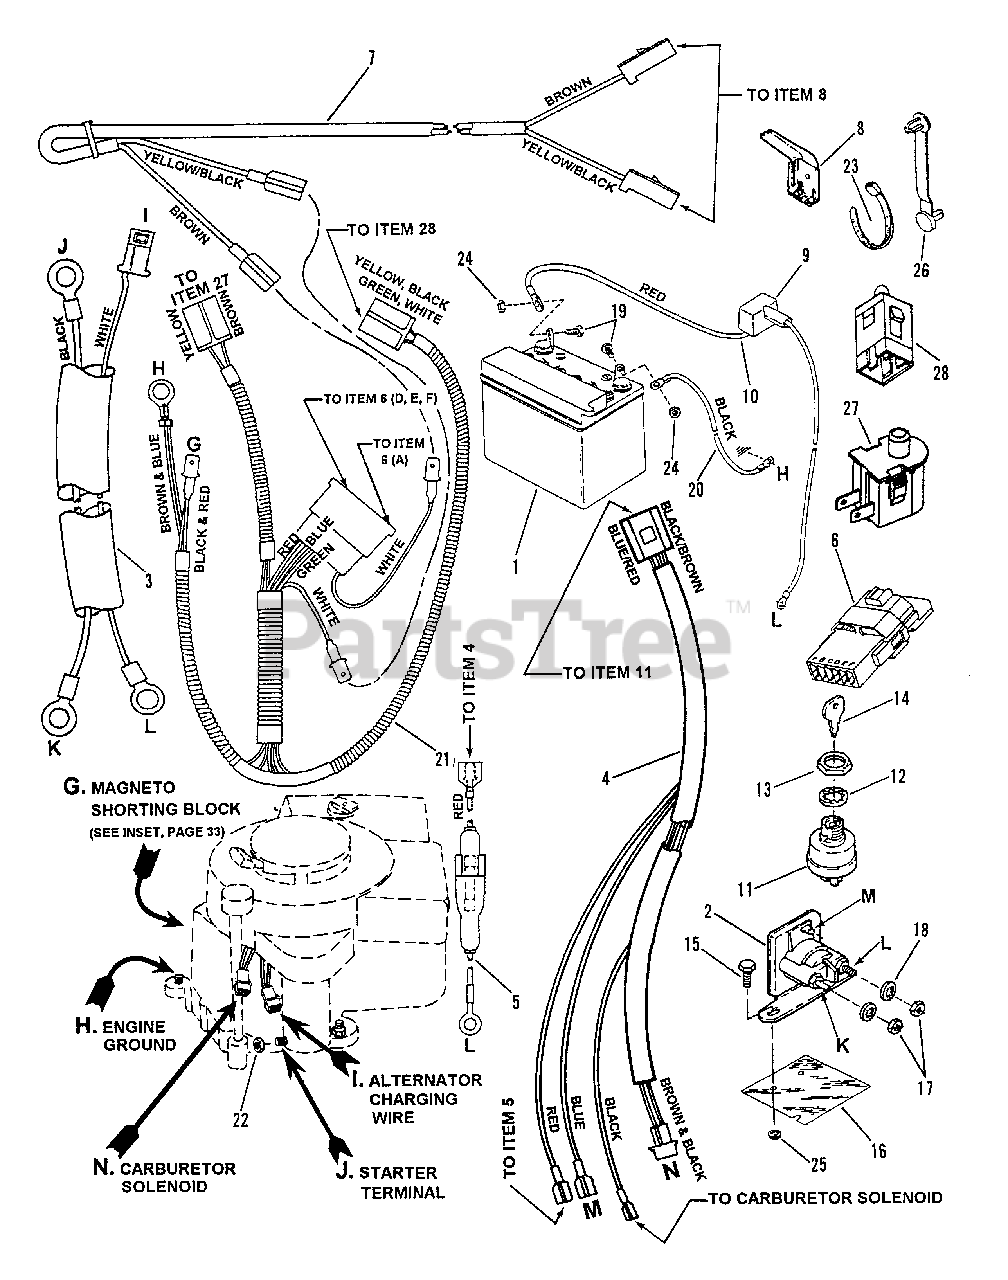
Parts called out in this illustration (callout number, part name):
1	KIT, 12V Dry Charge Battery
2	SOLENOID
3	HARNESS, Starter Wiring
4	HARNESS, Ignition Wiring
5	HOLDER, Fuse
6	INTERLOCK Module
7	HARNESS, (Deck Interlock Wiring)
8	SWITCH, Deck Interlock
9	COVER, Battery Cable
10	CABLE, Positive (Red)
11	SWITCH, Ignition
12	WASHER, 5/8 Internal Tooth Lock
13	NUT, 5/8-32 Hex
14	KEY, Switch
15	SCREW, 1/4-20 x 1/2" Self-Tapping
16	PROTECTOR, Solenoid
17	NUT, 1/4-20 Hex
18	WASHER, 1/4 Internal Tooth Lock
19	SCREW, 1/4-20 x 5/8" Hex Head Cap
20	CABLE, Negative
21	HARNESS, Operator Presence Control Wire
22	NUT, 1/4-20 Hex
23	TIE, 7" Long Cable
24	NUT, 1/4-20 Hex Lock
25	RETAINER, 1I4 Bolt
26	TIE, 2" Long Cable
27	SWITCH, Seat
28	SWITCH, Operator Presence Control Traction
